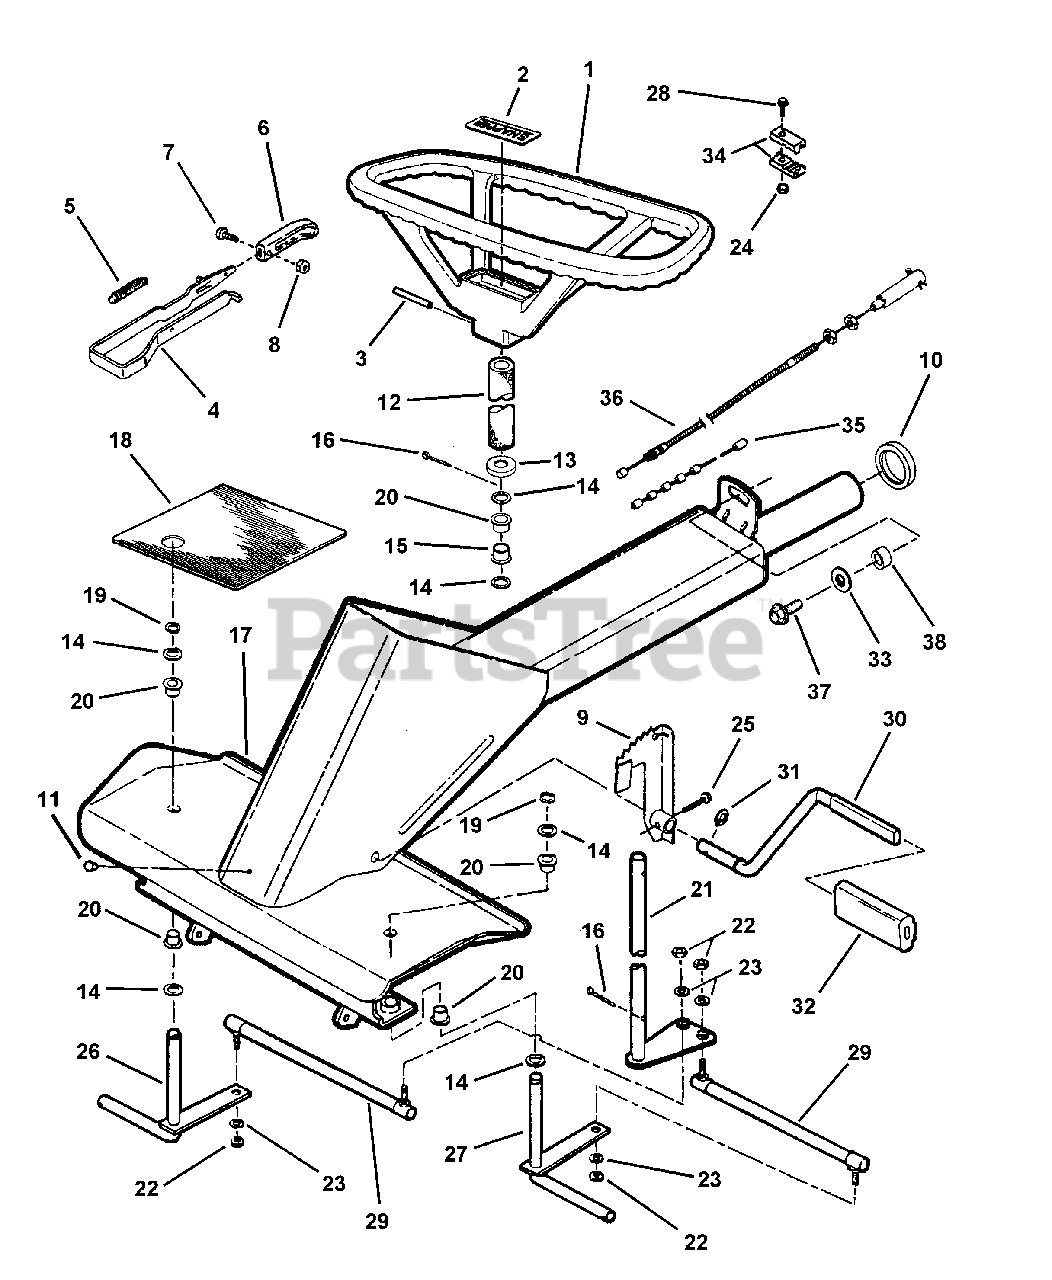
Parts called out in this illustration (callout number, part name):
1	ASSEMBLY, Steering Wheel
2	DECAL, Snapper
3	PIN, 1/4 x 1-1/2" Roll
4	LEVER, Clutch/Brake
5	SPRING
6	KNOB
7	SCREW, #8-32 x 3/8" Cross Recess
8	NUT, #8-32 Hex, Grade 2B
9	ARM, Clutch/Brake
10	SPACER, Main Tube
11	FASTENER/PLUG, Panel
12	COVER, Steering Shaft (Foam)
13	COVER
14	WASHER, 3/4 Flat
15	BUSHING, 3/4" Steering Shaft
16	COTTER-PIN, 3/16 x 1-1/2"
17	FRAME, Front (Wide, 19" @ King Pin Holes)
18	PAD, Foot
19	RING, 5/8" External Retaining
20	BEARING
21	SHAFT, Steering (Wide Front End)
22	NUT, 5/16-24 Hex, Grade 5
23	WASHER, 5/16 Split Lock
24	NUT, 1 /4-20 Hex Center Lock, Grade 5 or B
25	SCREW, 5/16-18 x 1-1/4" Hex Washer Head, Self-Tap
26	PIN, Wide King (Right Side)
27	PIN, Wide King (Left Side)
28	SCREW, 1 /4-20 x 3/4" Hex Head Cap, Grade 5
29	TIE-ROD 9.13"
30	PEDAL, Clutch/Brake
31	RING, 5/8" External Retaining
32	PAD, Clutch/Brake Pedal
33	WASHER, 3/8" Flat
34	UNION, Cable
35	CABLE, Clutch 48.71" Long
36	CABLE, Brake, Snap-in
37	SCREW, 3/8-16 x 5/8" Hex Washer Head, Self-Tap
38	SPACER, 25/64 x 5/8 x 3/16"
